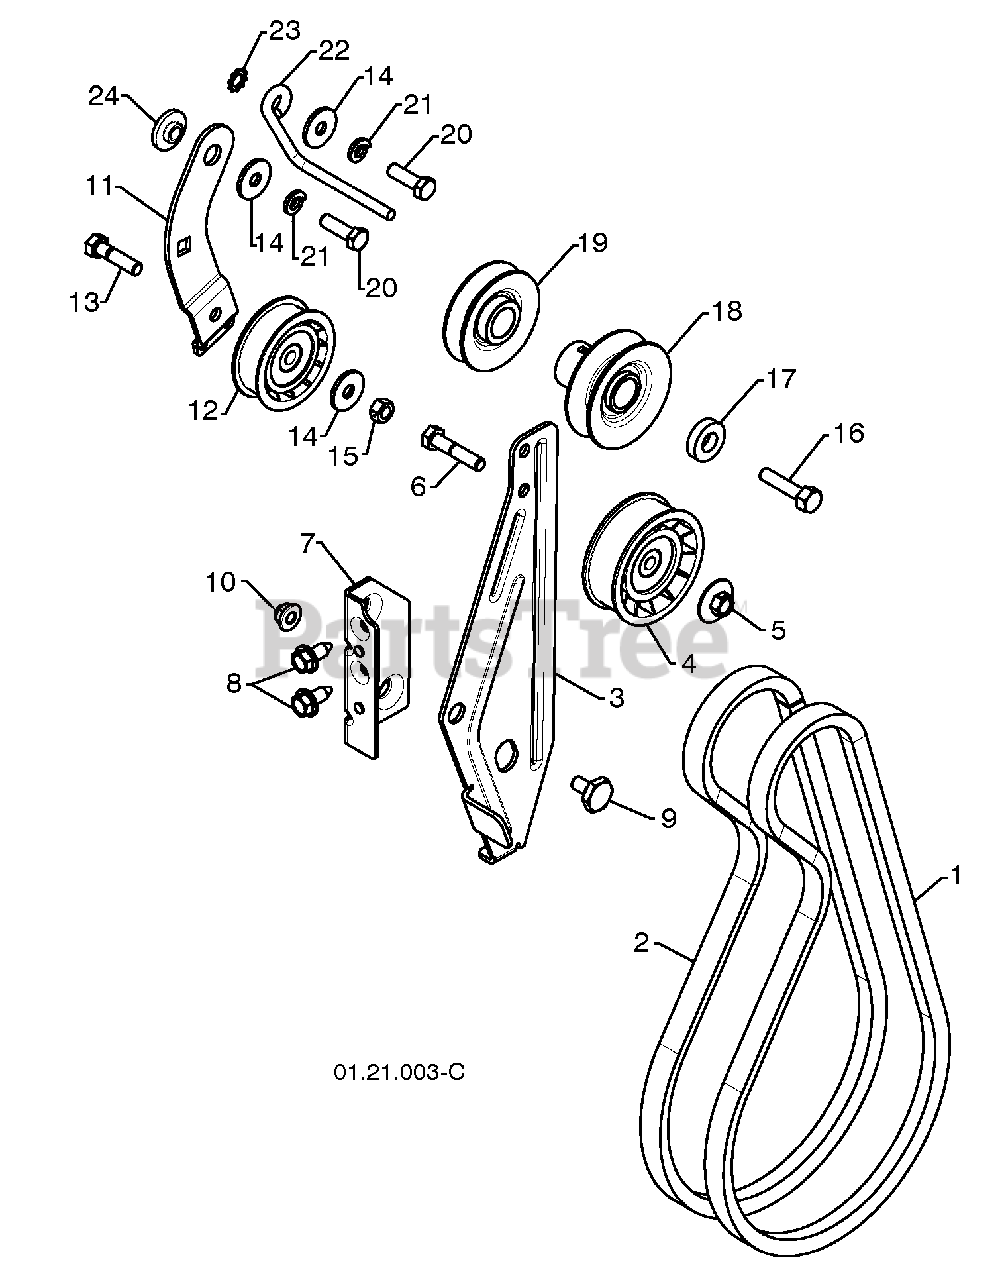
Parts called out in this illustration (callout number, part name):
1	IMPELLER BELT
2	TRACTION BELT
3	IDLER ARM BRACKET
4	IDLER PULLEY
5	NUT 5/16-18
6	SCREW 5/16-18 X 1 .50
8	SCREW 5/16-18 X .625
9	SHOULDER BOLT 5/16-18 X .500
10	NUT 5/16-18 NYLOCK
11	TRACTION IDLER ARM
12	TRACTION PULLEY
13	SCREW 5/16-18 X 1 .00
14	WASHER
15	NUT 5/16-18
16	SCREW 3/8-24 X 1.375
17	WASHER
18	PULLEY ENG IMPELLER
19	PULLEY ENG TRACTION
20	SCREW 5/16-18 X 1 .00
21	LOCKWASHER 5/16
22	BELT GUIDE
23	LOCKWASHER 5/16
24	IDLER BUSHING
